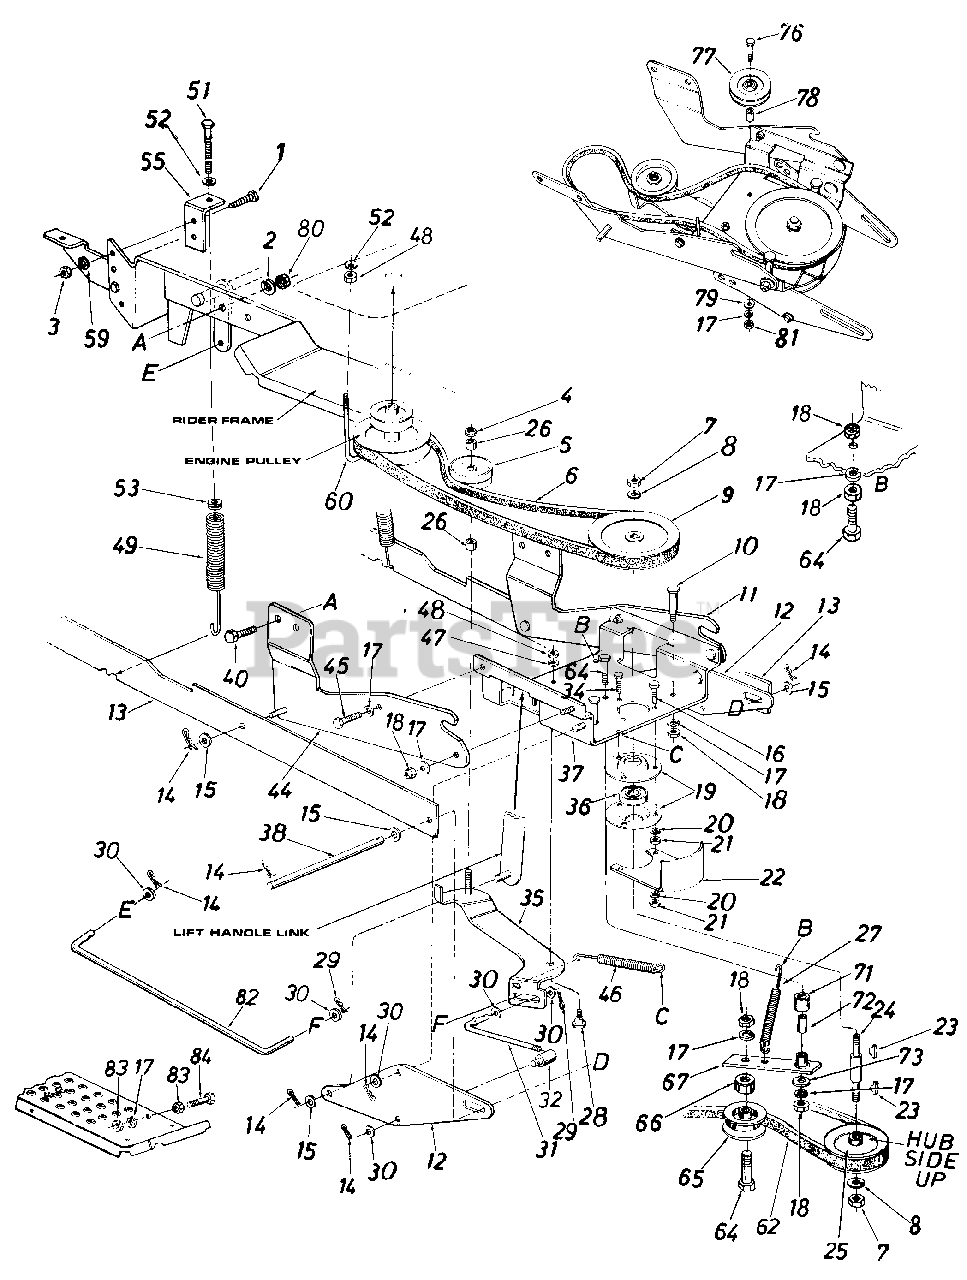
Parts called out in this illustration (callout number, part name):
1	Hex Bolt 1/4-28 x 1.00" Lg. Grade 5
2	L.-Wash. 1/4" I.D.
3	Hex Nut 1/4-28 Thd.
4	Hex Cent. L-Nut 3/8-16 Thd.
5	Idler Pulley
6	"V" Belt
7	Hex Jam Nut 5/8-11 Thd.
8	L.-Wash. 5/8" I.D.
9	6.50" O.D. x 5/8 Pulley
10	Shoulder Bolt
11	Channel Support Brkt.-R.H.
12	Linkage Brkt.
13	Linkage Arm Ass'y.
14	Intern. Cotter Pin .50 Dia.
15	Fl.-Wash.
16	Hex Bolt 5/16 x 1.25" Lg.
17	L.-Wash. 3/8" I.D.
18	Hex Jam Nut 3/8-16 Thd.
19	Bearir:g Housing
20	L.-Wash. 5/16" I.D.
21	Hex Nut 5/16-18 Thd.
24	Pulley Spindle
25	5/8 Pulley-6.28 I.D. x 5.56 O.D.
26	Spacer.383 I.D. x .503 O.D. x .562 Lg.
27	Extension Spring .54 O.D. x 5.25"
28	Shoulder Bolt
29	Cotter Pin 3/32" Dia.
30	Fl.-Wash.
31	Control Rod
32	Ferrule
34	Hex Sems Scr. 5/16-18 x .75" Lg.
35	Clutch Idler Brkt. Ass'y.
36	Ball Bearing
37	Channel Ass'y.
38	Lift Handle Shaft
40	Hex Self-Tap Scr. 1/4-20 x .75 " Lg .
44	Channel Supporting Brkt. L.H.
45	Hex Bolt 3/8-16 x 1.0" Lg.
46	Extension spring
47	L.-Wash. 5/16" I.D.
48	Hex Nut 5/16-18 Thd.
49	Helper Spring
51	Hex Scr. 5/16-18 x 2.0" Lg. Special
52	Bell Wash. .345 I.D. x .88 O.D. x .06
53	Spring Insert
60	J.-Bolt 5/16-18 Thd.
62	"V"Belt 1/2 "A" x .89" Lg.
64	Hex Bolt 3/8-16 x 2.0" Lg .
65	Idler Pulley
66	Spacer .385 I.D. x .503 O.D. x .562" Lg.
67	Idler Arm Ass'y.
71	Spacer .380" I.D.
72	Spacer .3775 I.D. x .60 O.D. x 8.3 Lg.
73	Fl.-Wash. 3/8 I.D. x l" O.D. x 1.27
76	Hex Bolt 3/8-16 x 2.5" Lg. (Grade 5)
77	Idler Pulley .38 I.D. x 3.06 O.D.
78	Spacer .385 I.D. x .630 O.D. x .76 Lg.
79	Fl.-Wash. .39 I.D. x 1-3/4 O.D. x 3/16"
80	Hex L-Nut 1/4-20 Thd.
81	Hex Nut 3/8-16 Thd.
82	Clutch Control Rod
83	Hex Nut 3/8-24 Thd.
84	Hex Bolt 3/8-24 x 2.25" Lg.
